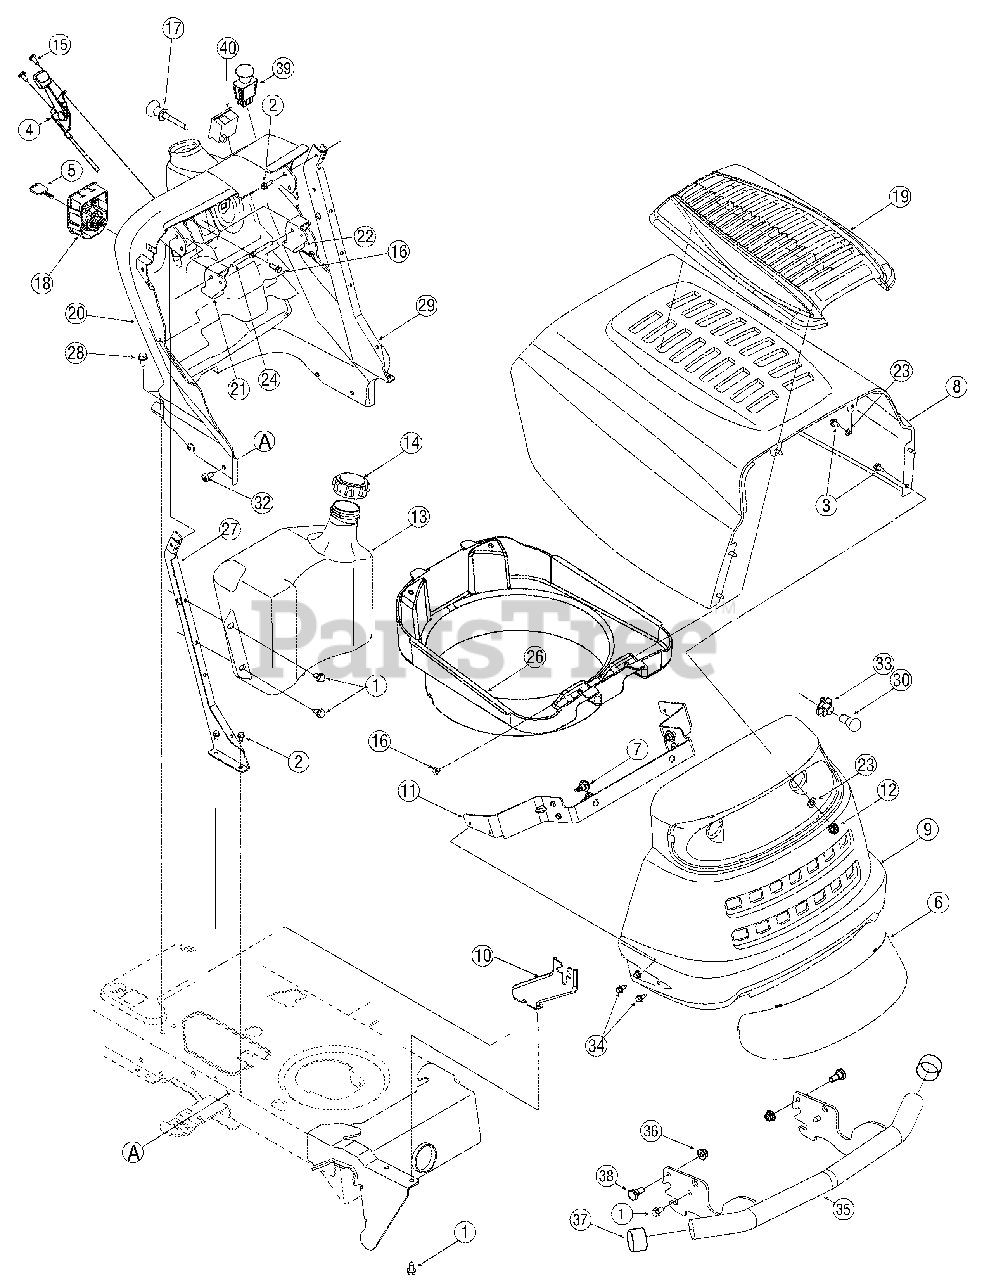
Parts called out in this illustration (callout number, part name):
1	Screw, 5/16-12 x .750
2	Self-tapping Screw, 1/4-20 x.5
3	Hex Cap Screw, 1/4-20 x.62
4	Throttle Control/Cable
5	Ignition Key w/ plastic cover
5	Ignition Key w/o plastic cover
6	Headlight Lens
7	Shoulder Screw,.43 x.29
13	Fuel Tank, Two Gallon
13	Fuel Tank, Three Gallon
14	Fuel Cap
15	Screw, 1/4-14 x.625
16	Self-tapping Screw, 1/4-15 x.75
17	Choke Control Cable
18	Ignition Switch
19	Hood Cover, 5 Style
20	Dash Panel
21	Cruise Control Button
22	Parking Brake Button
23	Flat Washer, .265 x .938 x 1.20
24	Brake/Cruise Pivot Rod
30	Lamp
31	Bell Washer,.265 x.75 x.062
32	Screw, 5/16-18 x.75
33	Headlight Socket
34	Hex Index Screw, 1/4-20 x.625
36	Flange Lock Nut, 3/8-16
38	Shoulder Bolt, 3/8-16
39	Electric PTO Switch
40	Systems Ind. Monitor w/Hr. Mtr.
40	Systems Ind. Monitor w/ Amtr.
